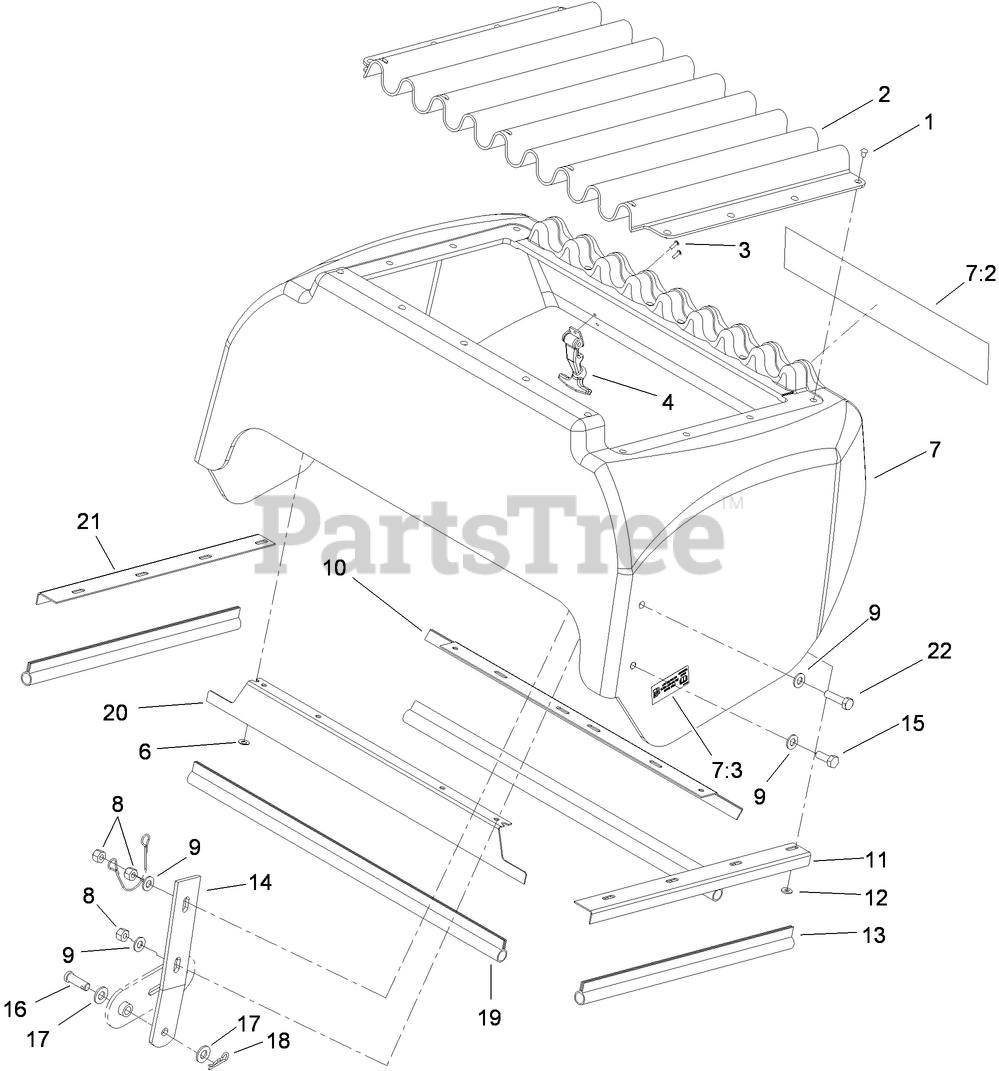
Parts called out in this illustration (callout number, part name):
2	SCREEN-RADIATOR
3	RIVET
4	LATCH-RUBBER
6	WASHER-SPRING
7	HOOD ASM
7:3	DECAL-LOW SULFUR
8	NUT-LOCK, NI
9	WASHER-PLAIN
10	ANGLE-RADIATOR, BOTTOM
11	ANGLE-RADIATOR, LH
12	WASHER-FLAT
13	SEAL-TRIM
14	PLATE-HINGE, HOOD
15	SCREW-HH
16	PIN-CLEVIS
17	WASHER-FLAT
18	PIN-COTTER
19	SEAL-TRIM
20	ANGLE-RADIATOR, TOP
21	ANGLE-RADIATOR, RH
22	SCREW-HH
